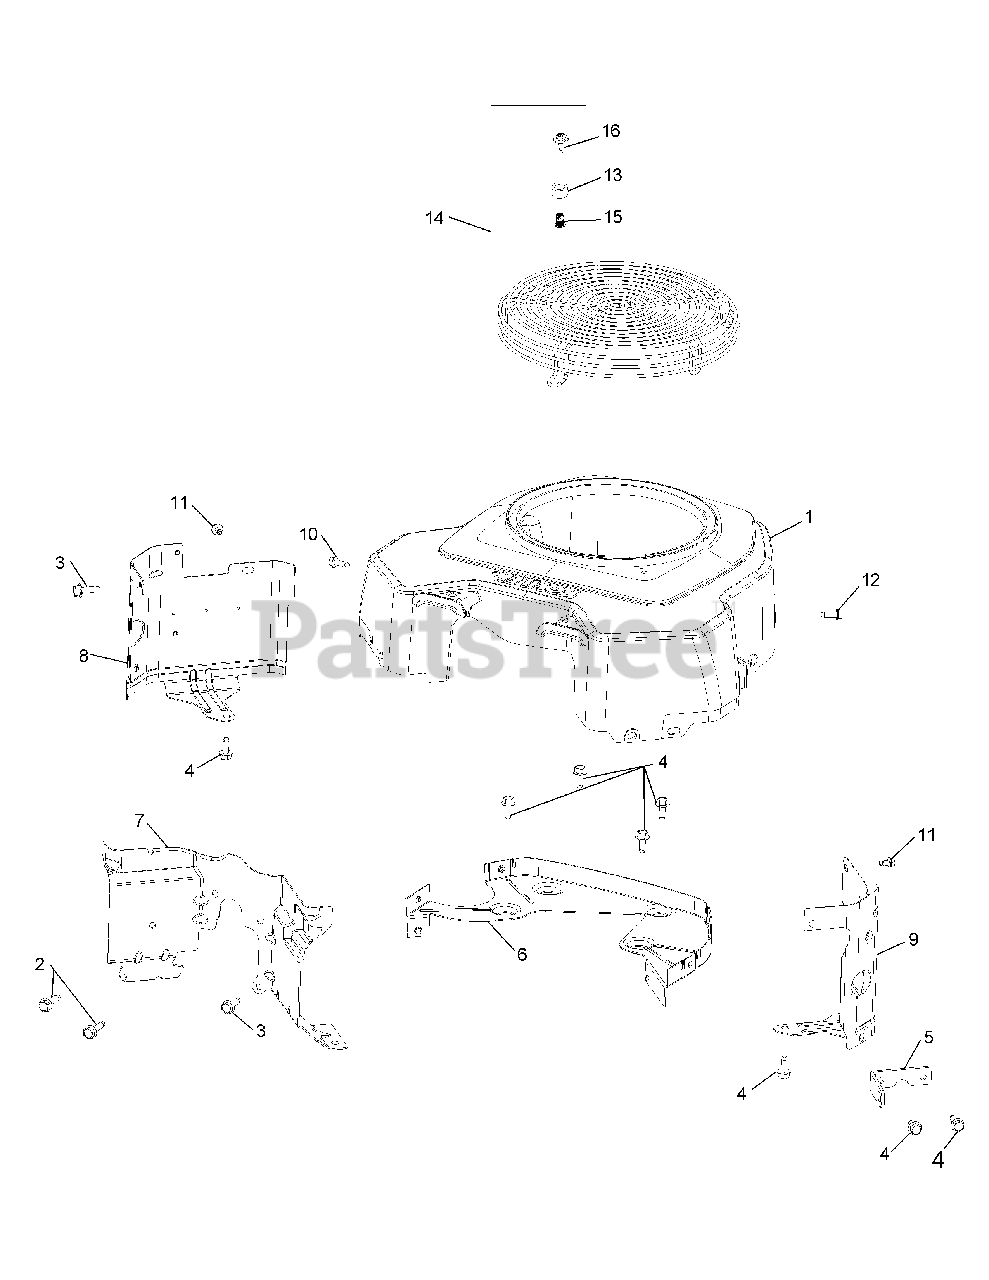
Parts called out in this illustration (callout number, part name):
1	Blower Housing
2	Thread Forming Screw
3	Thread Forming Screw
4	Thread Forming Screw
6	Backing Plate Kit
8	Cylinder Barrel Kit, #1 Side
9	Cylinder Baffle Kit, #2 Side
10	Thread Forming Screw
11	Thread Forming Screw
12	Thread Forming Screw
15	Threaded Insert
